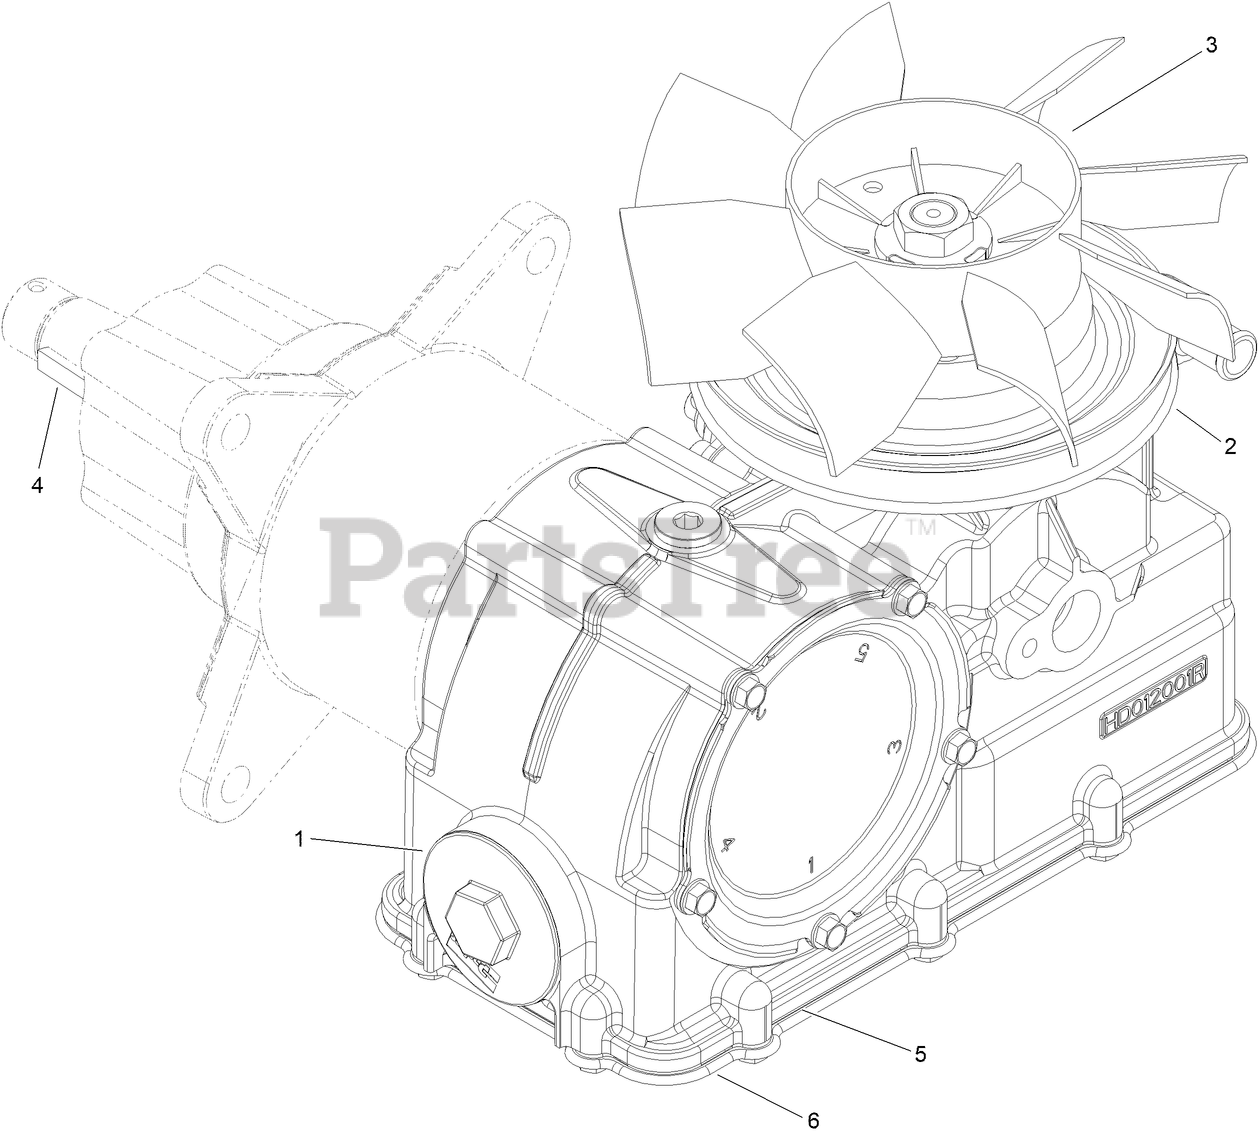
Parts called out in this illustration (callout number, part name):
1	FILTER
2	PULLEY
3	FAN (8.3 INCH)
4	KEY-WOODRUFF
5	GASKET-COVER, BOTTOM
6	COVER-SERVICE
